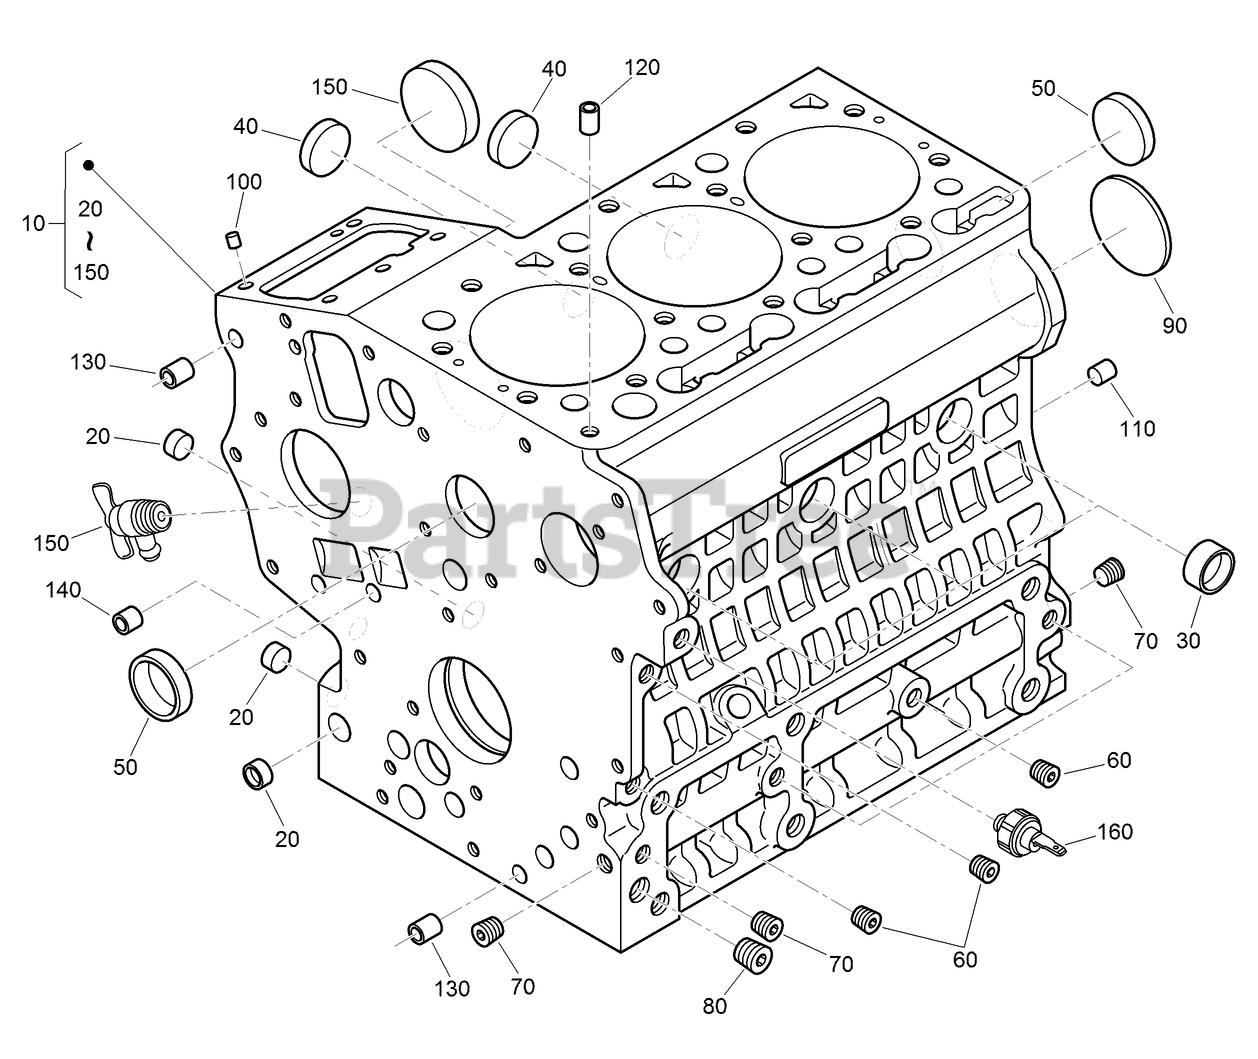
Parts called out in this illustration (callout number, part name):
10	CRANKCASE ASM
20	CAP-SEALING
30	CAP-SEALING
40	CAP-SEALING
80	PLUG-EXPANSION
90	PIN-STRAIGHT
100	PIN-STRAIGHT
110	PIN-PIPE
120	PIN-PIPE
130	PIN-PIPE
140	COVER-FUEL, CAMSHAFT
150	DRAINCOCK ASM
160	SWITCH-OIL
